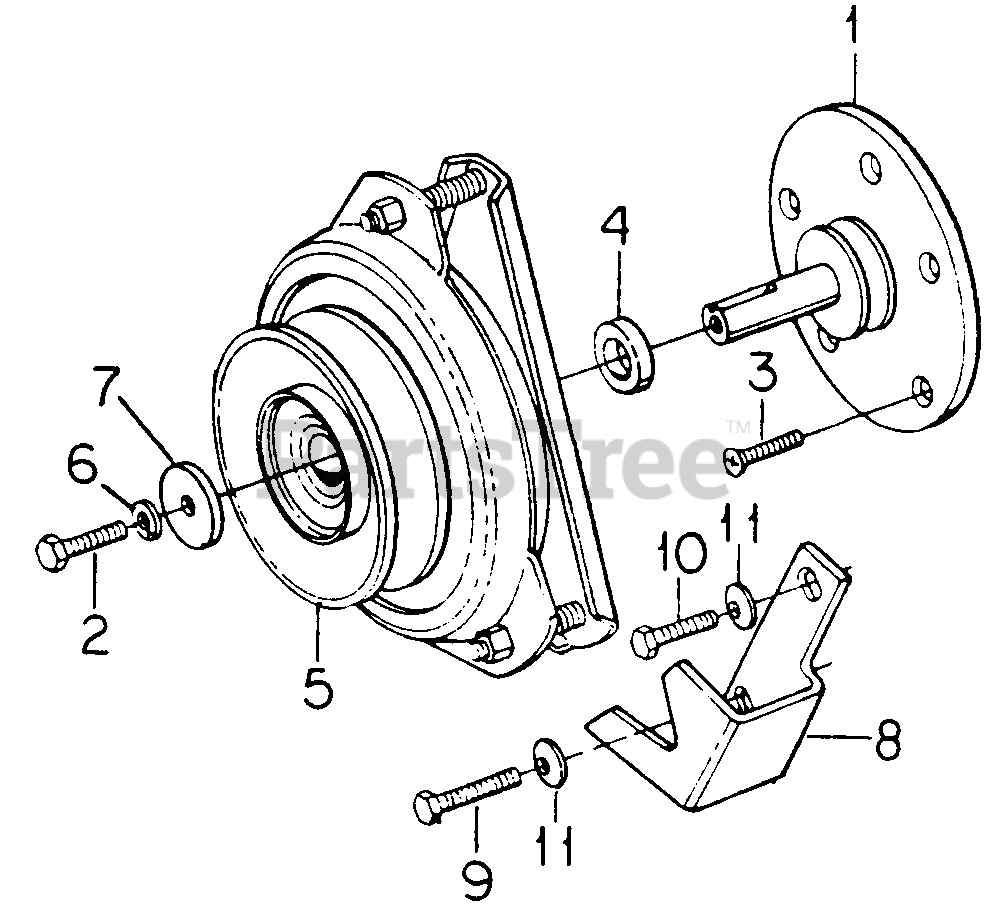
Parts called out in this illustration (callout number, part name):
1	Shaft, Stub
2	Bolt, 3/8-NF X 1 Type 5
3	Screw, M8 X 19 F/Hd Ctsk W/Patch
5	Clutch Assy, PTO
6	Washer, 3/8 Lock
7	Washer, .406 X 1.5 X 1.50
8	Bracket, Torque
9	Bolt, 5/16-NF X 1 Type 5
10	Bolt, M8 X 20 Phc Class 8.8
11	Washer, Bell
